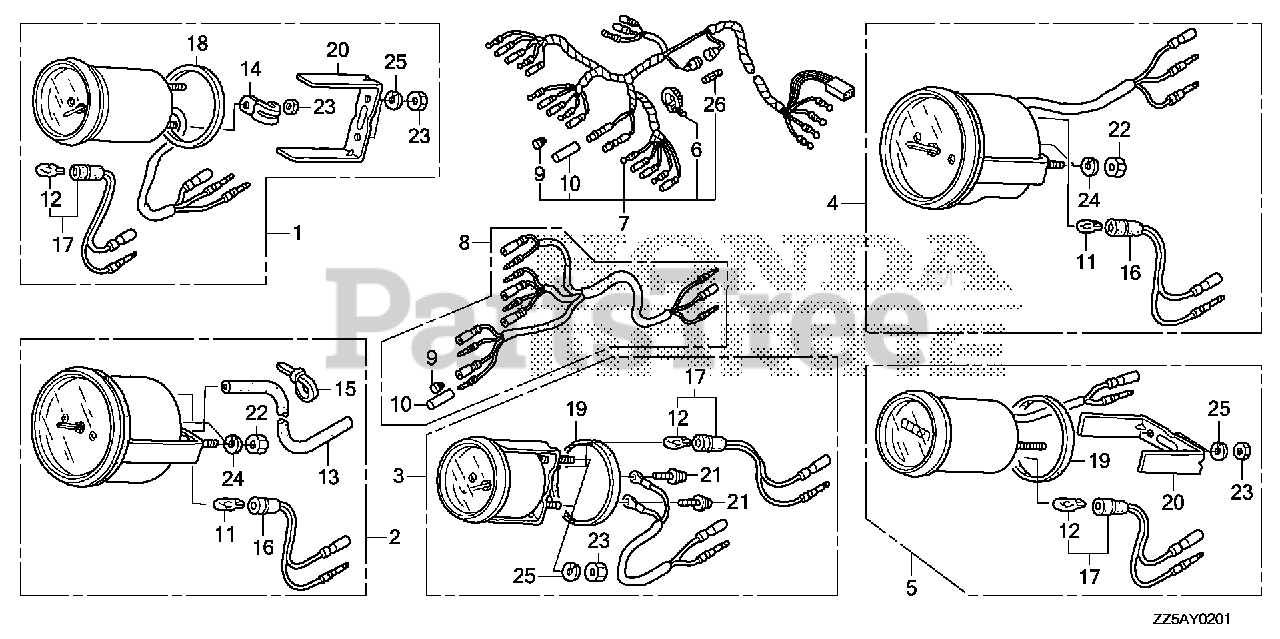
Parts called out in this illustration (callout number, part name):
1	METER KIT, TRIM
1	METER KIT, TRIM (B)
2	SPEEDOMETER KIT
2	SPEEDOMETER KIT (B)
3	METER KIT, VOLT
3	METER KIT, VOLT (B)
4	METER KIT, TACHO
4	METER KIT, TACHO (B)
5	METER KIT, HOUR (NA USE ALT:39700-ZW5-000ZA)
5	METER KIT, HOUR (B) (NA USE ALT:39700-ZW5-000ZA)
6	BAND B1, WIRE
7	HARNESS ASSY., METER (A)
8	HARNESS ASSY., METER (B)
9	PLUG, CONNECTOR (INNER)
10	PLUG, CONNECTOR (OUTER)
11	BULB, WEDGE BASE (T10) (12V 1.7W) (STANLEY)
12	BULB, WEDGE BASE (12V 1.7W)
13	TUBE, SPEED METER (4X7X8000)
14	CLAMP
15	BAND, SELF-LOCK
16	SOCKET
17	SOCKET
18	GASKET
19	GASKET
20	BRACKET
21	SCREW-WASHER (3X22)
22	NUT, HEX. (5MM)
23	NUT, HEX. (4MM)
24	WASHER, SPRING (5MM)
25	WASHER, SPRING (4MM)
26	FUSE A (10A)
